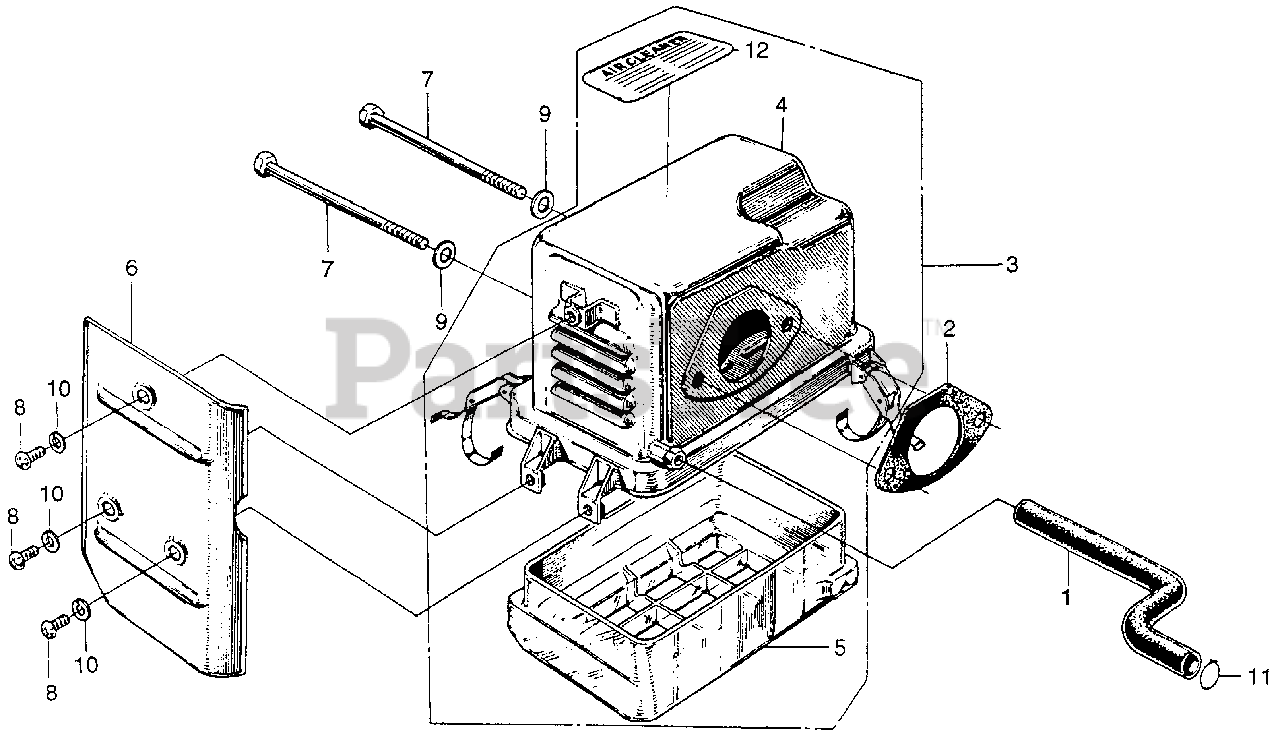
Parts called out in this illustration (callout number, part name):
1	TUBE, BREATHER (NOT AVAILABLE)
2	GASKET, AIR CLEANER (NOT AVAILABLE)
3	AIR CLEANER, BATH (NOT AVAILABLE)
4	BODY, CLEANER *R8* (BRIGHT RED)
6	PROTECTOR (NOT AVAILABLE)
7	BOLT, HEX. (6X90)
8	SCREW, PAN (4X8)
9	WASHER, PLAIN (6MM)
10	WASHER, SPRING (4MM)
11	CLIP, TUBE (B12.5)
11	CLIP, TUBE (C11)
12	PLATE, OIL BATH CAUTION
